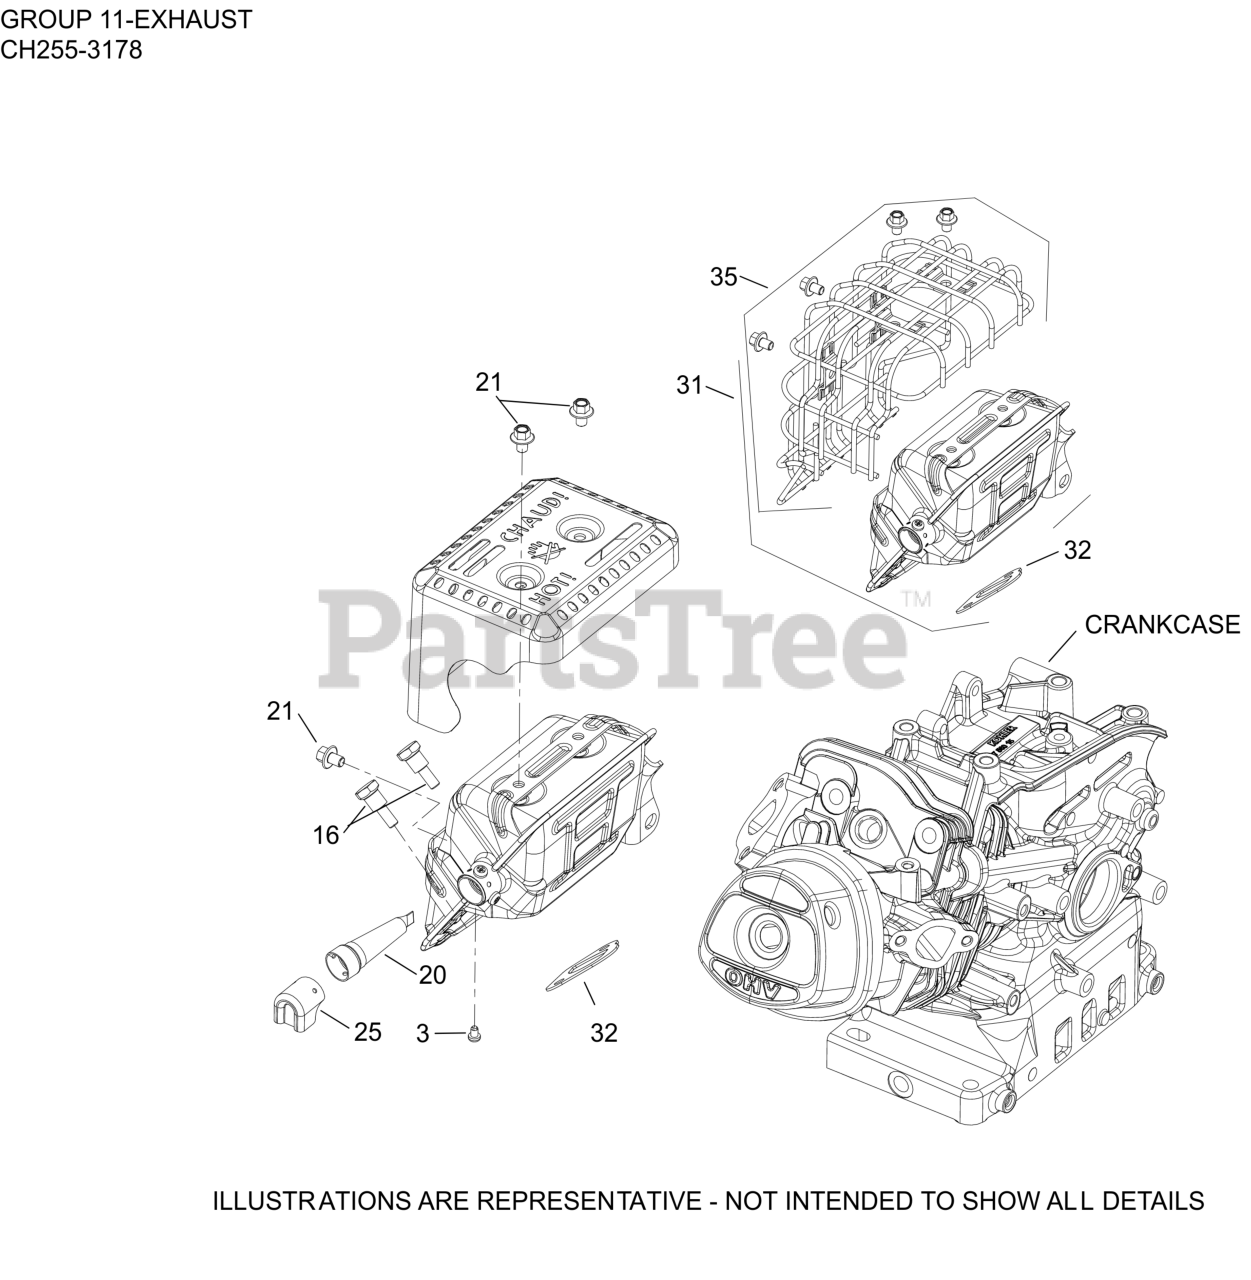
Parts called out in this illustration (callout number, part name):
3	SCREW, SPARK ARRESTOR
16	SCREW, SHOULDER
20	SPARK ARRESTOR, ASSEMBLY
21	SCREW, M6 X 8 HEX FLANGE HEAD
25	KIT, DEFLECTOR & SCREWS
31	KIT, MUFFLER
32	GASKET, MUFFLER
35	KIT, MUFFLER ASSEMBLY W/GUARD
